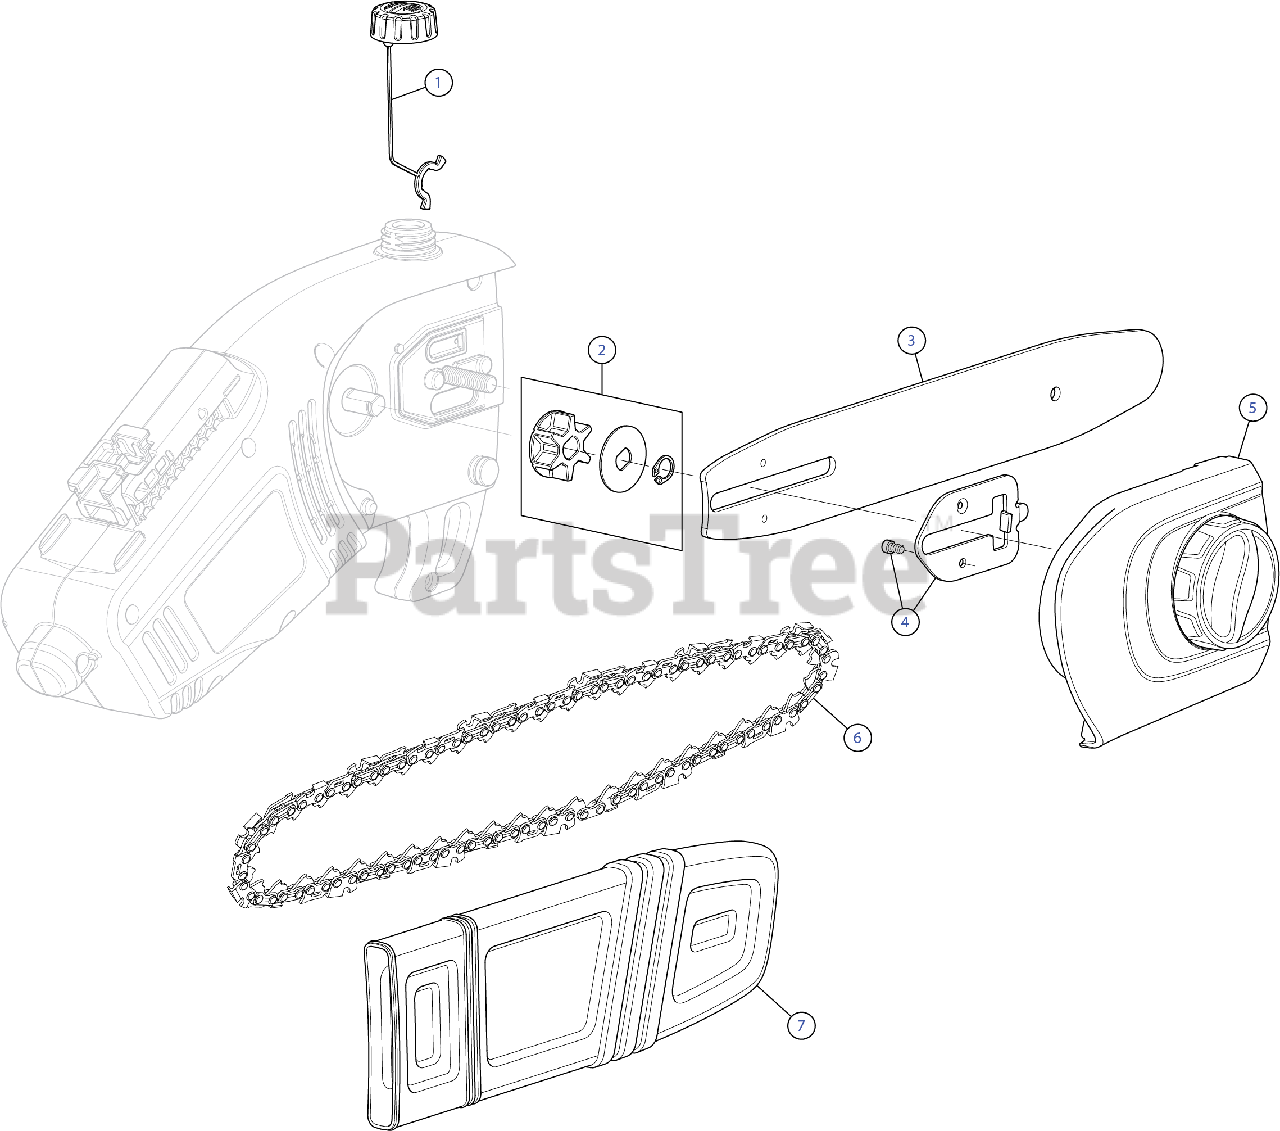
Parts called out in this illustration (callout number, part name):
1	OIL CAP ASM Q987U090089
2	SPROCKET KIT J3660000019R
3	BAR 10" TRI LINK M1501040-1041
4	PLATE ASM CAM ADJ J3700000015R
5	COVER ASM BAR Q03YA180089R
6	CHAIN 10" TRI LINKCL15040XPB
7	SCABBARD Q03YC950ZN7R
